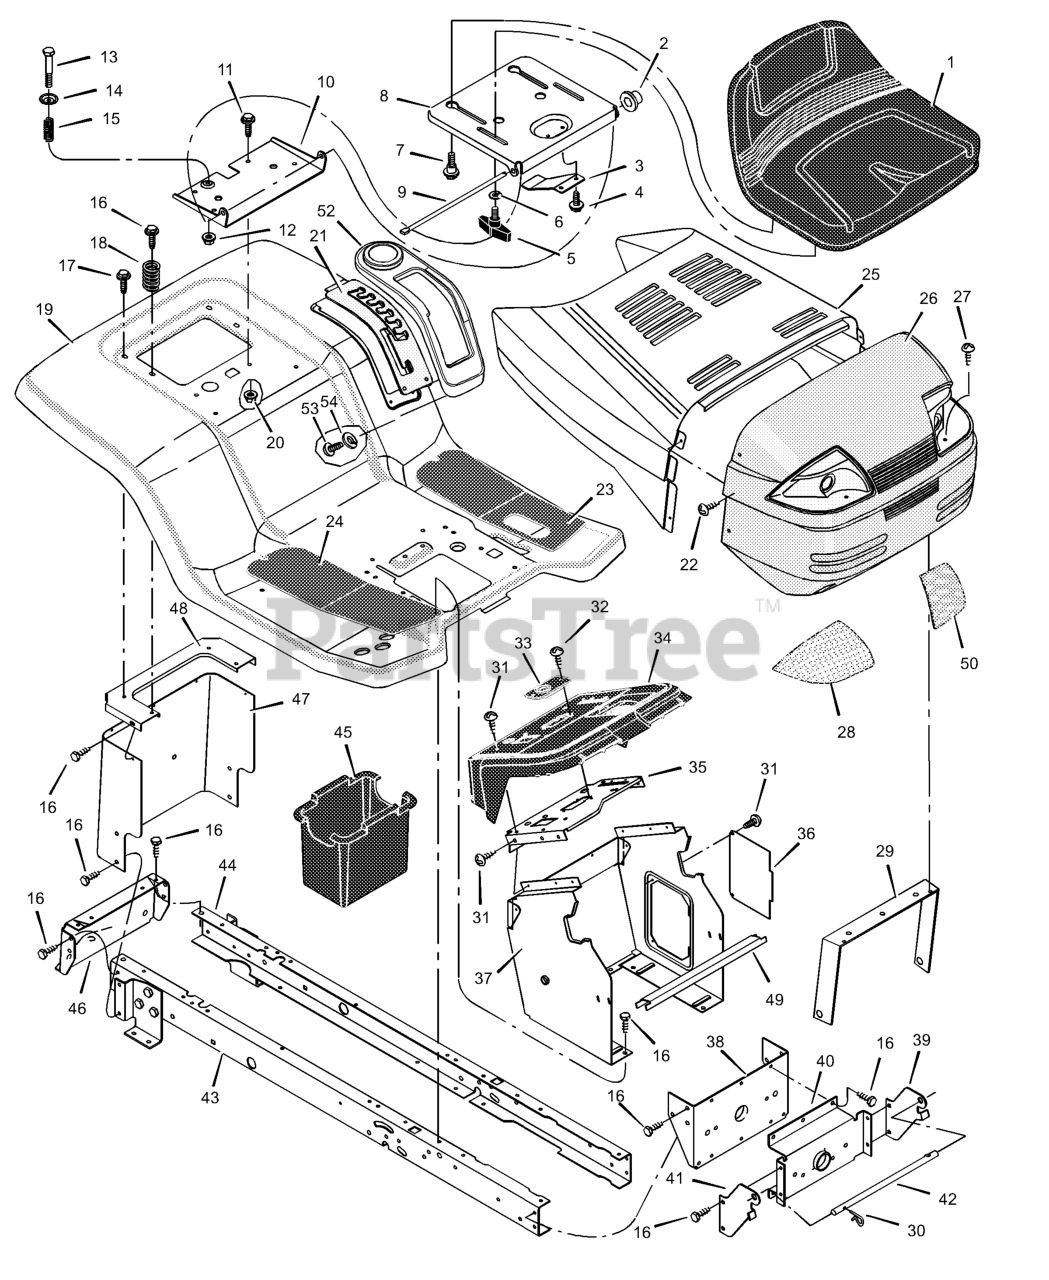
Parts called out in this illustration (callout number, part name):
2	Cap, Push On
5	Bolt, Wing
6	Washer
7	Bolt, Shoulder
8	Support, Seat
9	Rod, Pivot
10	Bracket, Pivot
11	Bolt
13	Bolt, Shoulder
15	Spring
19	Deck, Seat
20	Nut
21	Plate, Index
23	Mat, Left
24	Mat, Right
25	Hood
26	Grille Assembly
27	Screw
28	Lens, Right
29	Brace, Grille
30	Pin, Hair
31	Screw
33	Bearing, Steering
34	Dash (Grey)
35	Plate, Dash
36	Panel, Access
37	Support, Dash
38	Bracket, Rear Hanger
39	Support, Left Grille
40	Axle, Hanger
41	Support, Right Grille
42	Rod, Pivot
43	Frame, Right
44	Frame, Left
45	Container, Battery
46	Plate, Hitch
47	Plate, Rear
48	Top, Rear Plate
50	Lens, Left
52	Cover, Detent (with cup holder)
54	Washer
